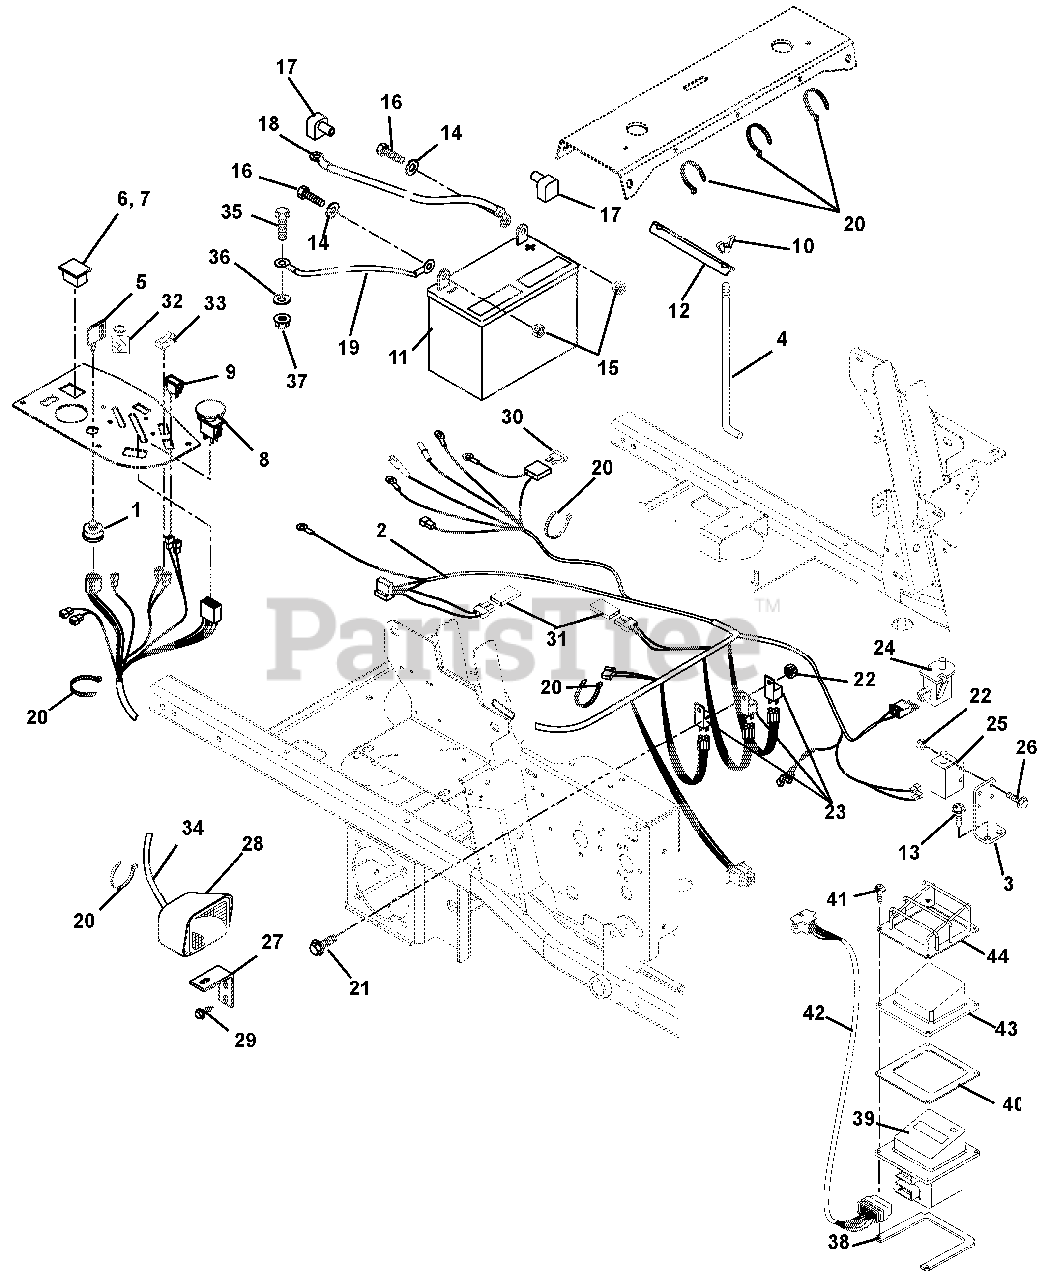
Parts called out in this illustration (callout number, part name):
1	Switch, Ignition
2	Harness, Z-6 Pin Wiring (EYE-Q) (045, 046, 047, 049, 052, 053, 066, 067, 068, 070, 071, 072)
3	Mount, Safety Switch
4	Rod, Battery Holddown .25 x 6.62
5	Key, with Shield
6	Plug (066, 067, 068, 069, 070, 071, 072)
7	Hour Meter (045, 046, 047, 048, 049, 049, 052, 053)
8	Switch, PTO Clutch
9	Light-Indicator Kit (045, 046, 047, 049, 052, 053, 066, 067, 068, 070, 071, 072)
10	Nut-Locking Wing .25-20
12	Hold Down
13	Screw-Tapping .25-20 x .50 Hex Washer Head
14	Washer-Flat-Steel .281 x .620 x .065
15	Nut-Locking-Top-Flange .25-20
16	Bolt-Hex .25-20 x .75 Grade 5
17	Battery Terminal Boot, Red
18	Starter Cable 13 in.
19	Ground Cable
20	Cable Tie
21	Screw-Machine 10-24 x .50 Hex Washer Head
22	Nut-Locking-Nylon 10-24 With Insert
23	Relay (Included with Harness)
24	Switch- Snap Mounting
25	Switch-Single Pole
26	Screw-Machine 10-24 x .75 Hex Washer Head
27	Bracket, Headlight Mounting Left
28	Headlight
29	Screw-Tapping .38-16 x .50 Hex Washer Head
30	Fuse, 30 Amp (Included with Harness)
31	Diode, Connector Shell
32	Key Chain
33	Switch, Light
34	Harness, Headlight Kit
35	Bolt-Hex .31-18 x .75 Grade 5
36	Washer-Flat-Steel .344 x .688 x .065
37	Nut-Locking-Top-Flange .31-18
38	Spacer, Enclosure Mounting (Bottom) (992066, 067, 068, 069, 071, 072)
39	Assembly, Eye-Q (992066, 067, 068, 069, 071, 072)
40	Gasket, Eye-Q (992066, 067, 068, 069, 071, 072)
41	Screw, Machine 10-24 x 1.00 (992066, 067, 068, 069, 071, 072)
42	Harness, Eye-Q (992066, 067, 068, 069, 071, 072)
43	Guard, Element (992066, 067, 068, 069, 071, 072)
44	Guard, Vinyl Eye-Q (992066, 067, 068, 069, 071, 072)
